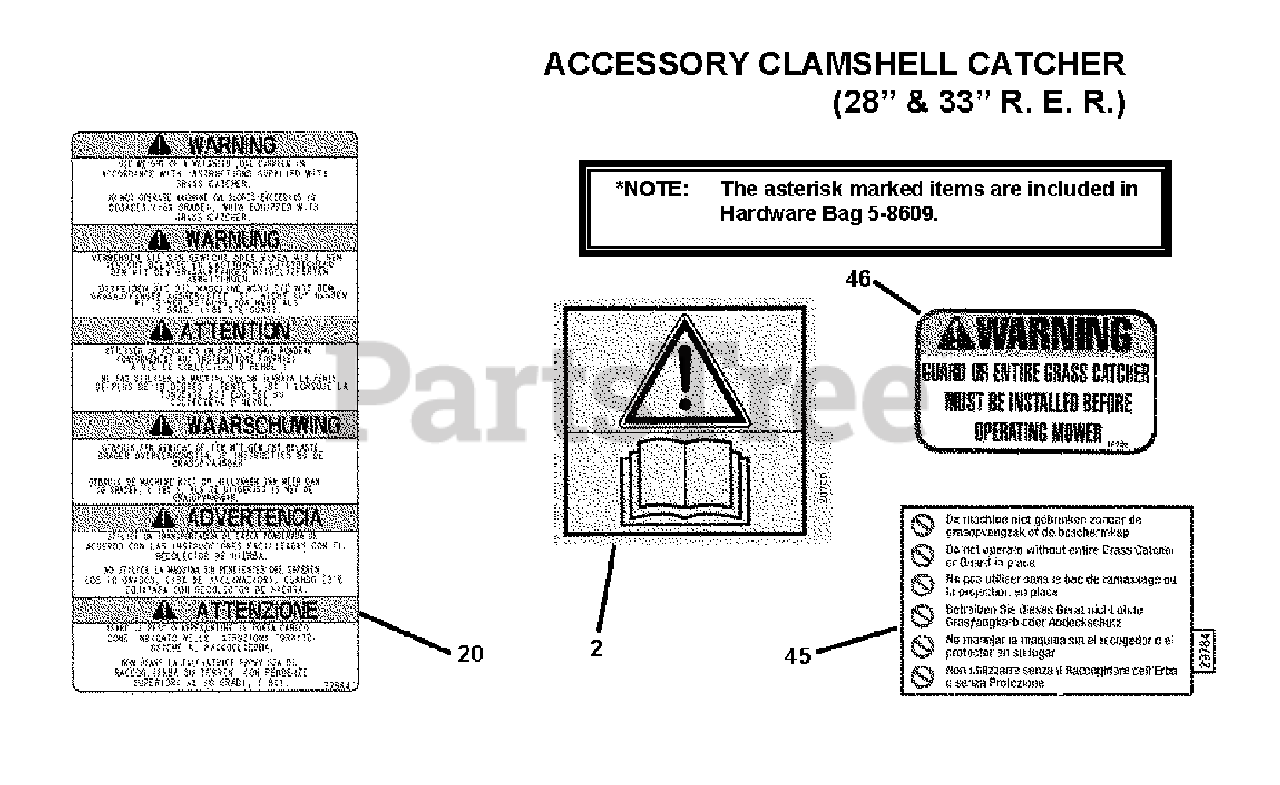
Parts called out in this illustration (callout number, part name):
2	DECAL, Read Manual
20	DECAL, Warning
45	DECAL, International Warning
46	DECAL, Chute/Deflector
